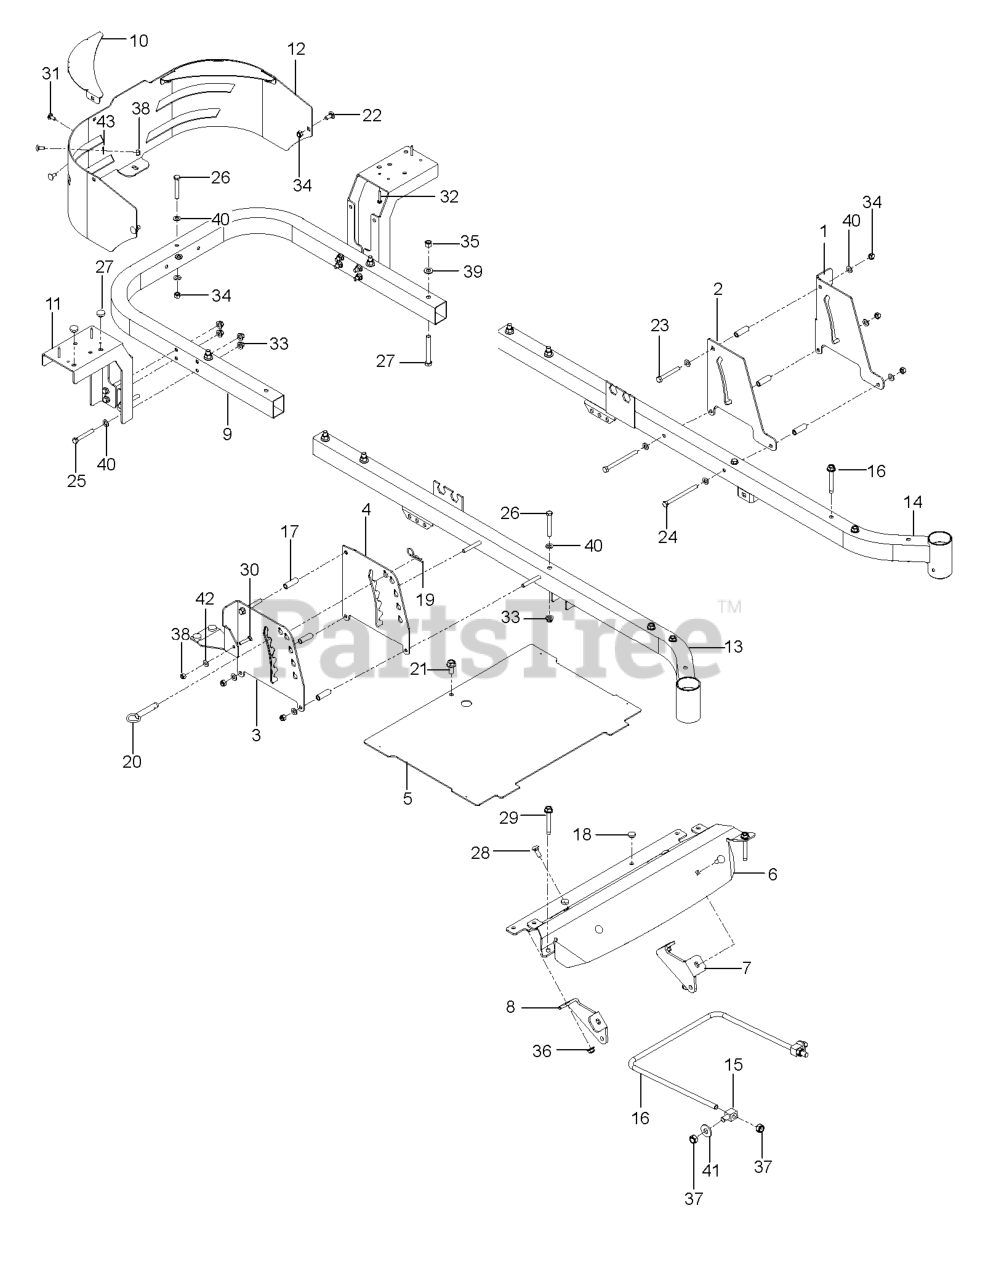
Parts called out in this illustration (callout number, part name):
1	PLATE, OUTER BRAKE, BLACK
2	PLATE, BRAKE LATCH, BLACK
3	PLATE, DECK HEIGHT, BLK EZ
4	PLATE, DECK HEIGHT, BLACK
5	PLATE, FOOT W/DECALS EZ
6	FOOT REST WIDE ORG
7	MOUNT, STRUT, RT, BLK
8	MOUNT, STRUT, LT, BLK
9	FRAME TUBE, REAR, ORANGE
10	SUPPORT, CORNER, ORANGE
11	SUPPORT, FENDER, BLACK
12	GUARD, REAR, ORANGE
12	WASH USS FLAT 1/2
13	FRAME, RT, ORANGE
14	FRAME, LT, ORANGE
16	LINK, FRONT SUSP.
17	SPACER, .334 ID X .5 OD X 1.5
18	GROMMET, BUMPER
19	HAIRPIN #4
21	HHFS 5/16-18 X 3/4
22	BOLT 5/16C X 3/4" CARRIAGE
23	HCS 5/16-18 X 2-1/2 GR 5 ZD
24	HCS 5/16C X 4
25	BOLT.FIN HEX 5/16-18UNC X2 1/4
27	BOLT.HEX.FIN.3/8-16 X 3.GR5
28	BOLT D
32	SCR #10-12X1-1/2HEX WASH HD ZD
33	5/16-18 NYLOC FLANGE NUT
34	NUT 5/16 NYLOC
35	NUT 3/8-16 NYLOC
36	NUT 3/8-16 HEX FLG NYLOC ZD
37	7/16-14 HEX NUT W/NYL RING ZD
38	NUT.1/4-20.HEX.NYLOC.ZD
39	WASHER 3/8 SAE FLAT
40	FLAT WASHER 5/16 SAE
41	WASH USS FLAT 1/2
42	WASHER 1/4 SAE
43	WASHER 1/4 FLAT
